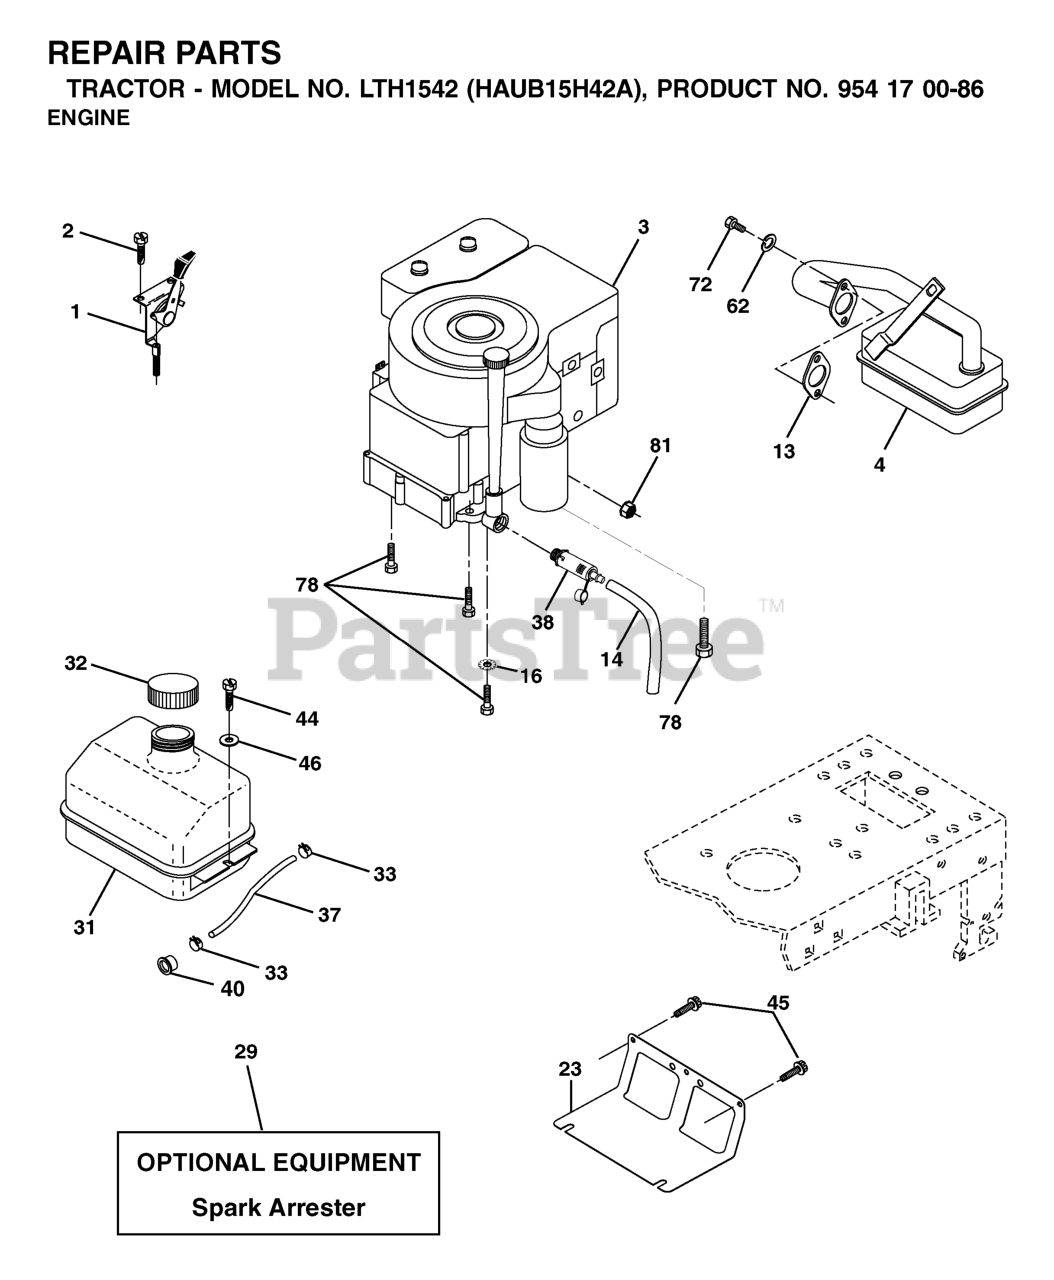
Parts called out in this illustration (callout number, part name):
1	BOLT 3/8-16 X 1.0
2	JAM NUT 1/4C (2 2 PW01)
3	BOLT 3/8-16 X 1 1/2 ZINC CLEAR
4	CLUTCH, WASHER
5	OIL DRAIN FITTING
6	CLUTCH 90 FT/LB OGURA
8	FUEL LINE 5"
9	HOSE CLAMP
10	HEX SCREW 7/16-20 X 3
11	WASHER 7/16 LOCK
12	WASHER, 3/8 ITLW ZN
13	NUT 3/8C CENTERBLOCK
